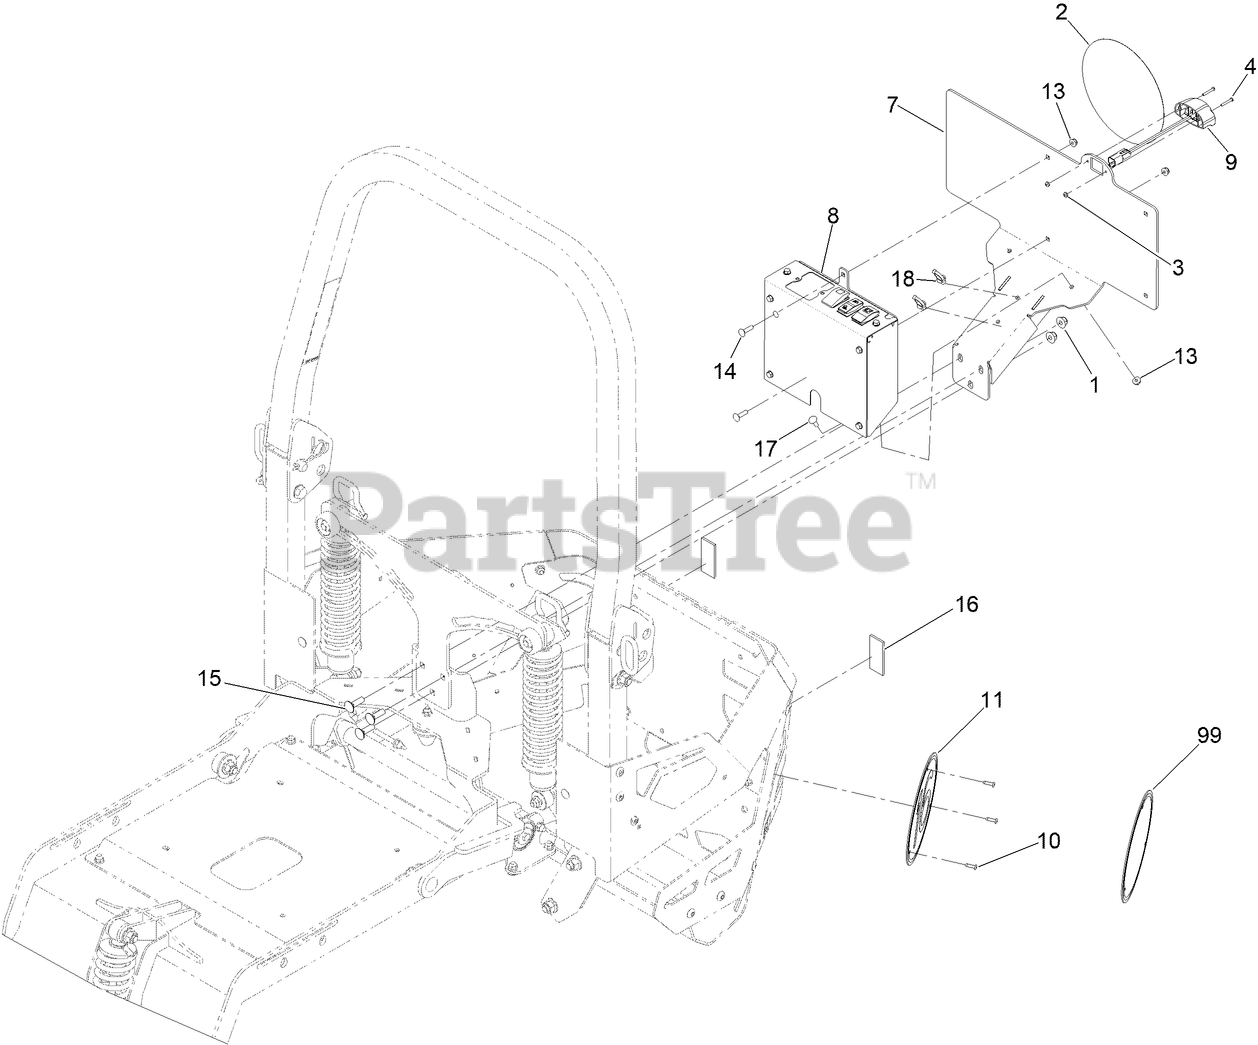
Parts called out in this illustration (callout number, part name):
1	NUT-HF, NI
2	SIGN-PVC
3	NUT-LOCK
4	SCREW-PPH
7	LICENSE-PLATE MOUNT ASM [BLACK]
8	CONTROL-LIGHTS, ASM
9	LIGHT-PLATE, LICENSE (ECE)
10	RIVET
11	SIGN-ALUMINUM, ROUND
13	NUT-HF
14	BOLT-CARRIAGE
15	BOLT-CARR
16	REFLECTOR-ADHESIVE
17	BOLT-CARR
18	CLIP-TIE
99	DECAL-SPEED, 10 KPH
